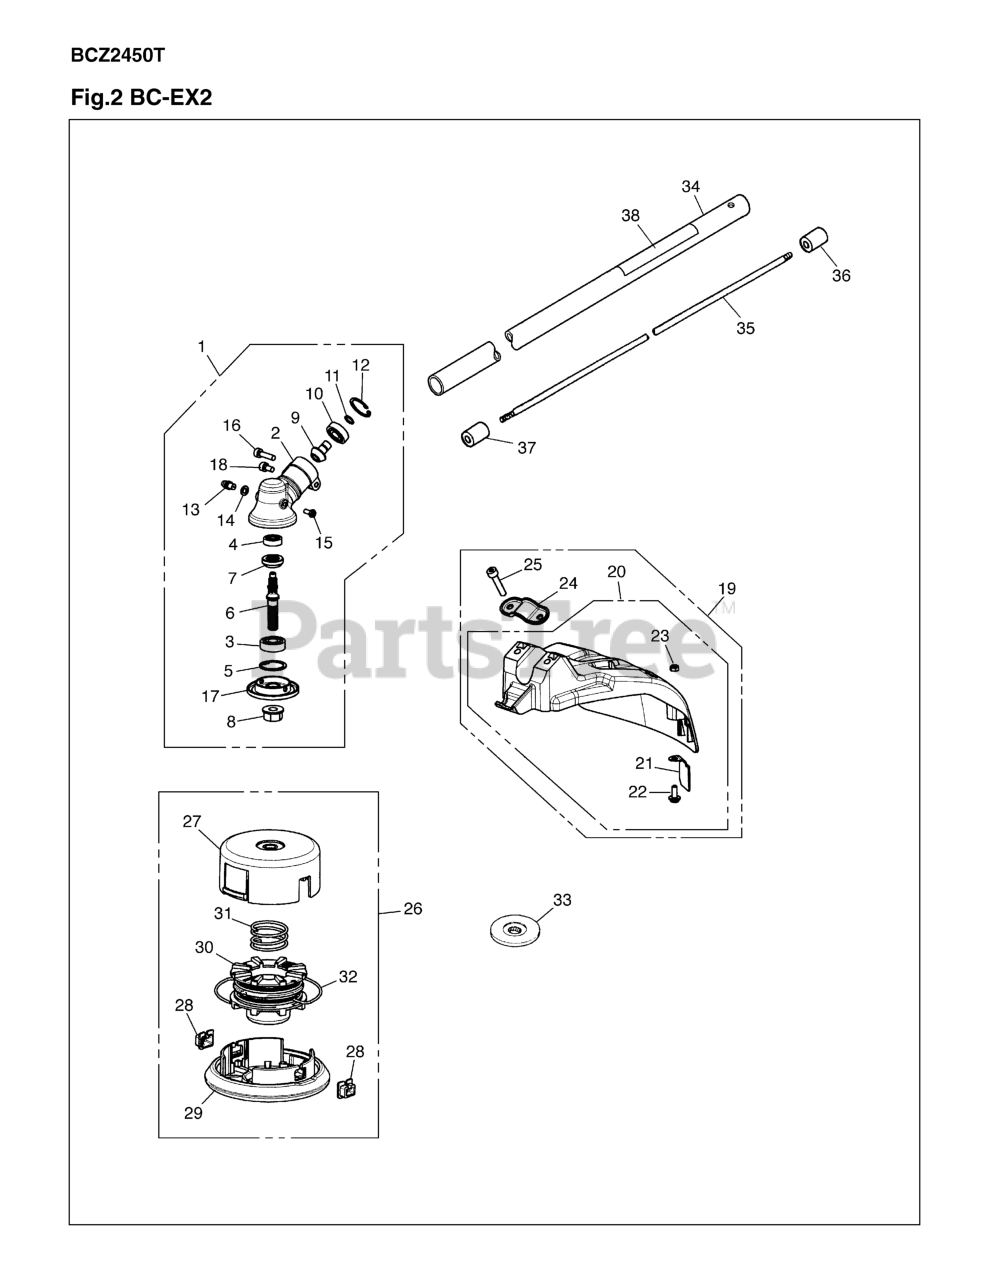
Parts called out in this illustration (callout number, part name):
1	GEARCASE ASSY.
2	GEARCASE
3	BEARING
4	BEARING
5	SNAP RING
6	SHAFT
7	GEAR
8	NUT
9	PINION
10	BEARING
11	SNAP RING
12	SNAP RING
13	FITTING, GREASE
14	WASHER, FITTING
16	BOLT TORX
17	HOLDER (A)
18	BOLT
19	GUARD ASSY
20	GUARD COMP.
21	BLADE
22	SCREW
23	NUT
24	CLAMP
25	BOLT
26	TAP HEAD COMP.
27	CASE
28	EYELET
29	COVER
30	CORD HOLDER
31	SPRING
32	CORD
33	HOLDER (B)
34	PIPE COMPLETE
35	SHAFT
36	SHAFT-JOINT
37	SPACER
